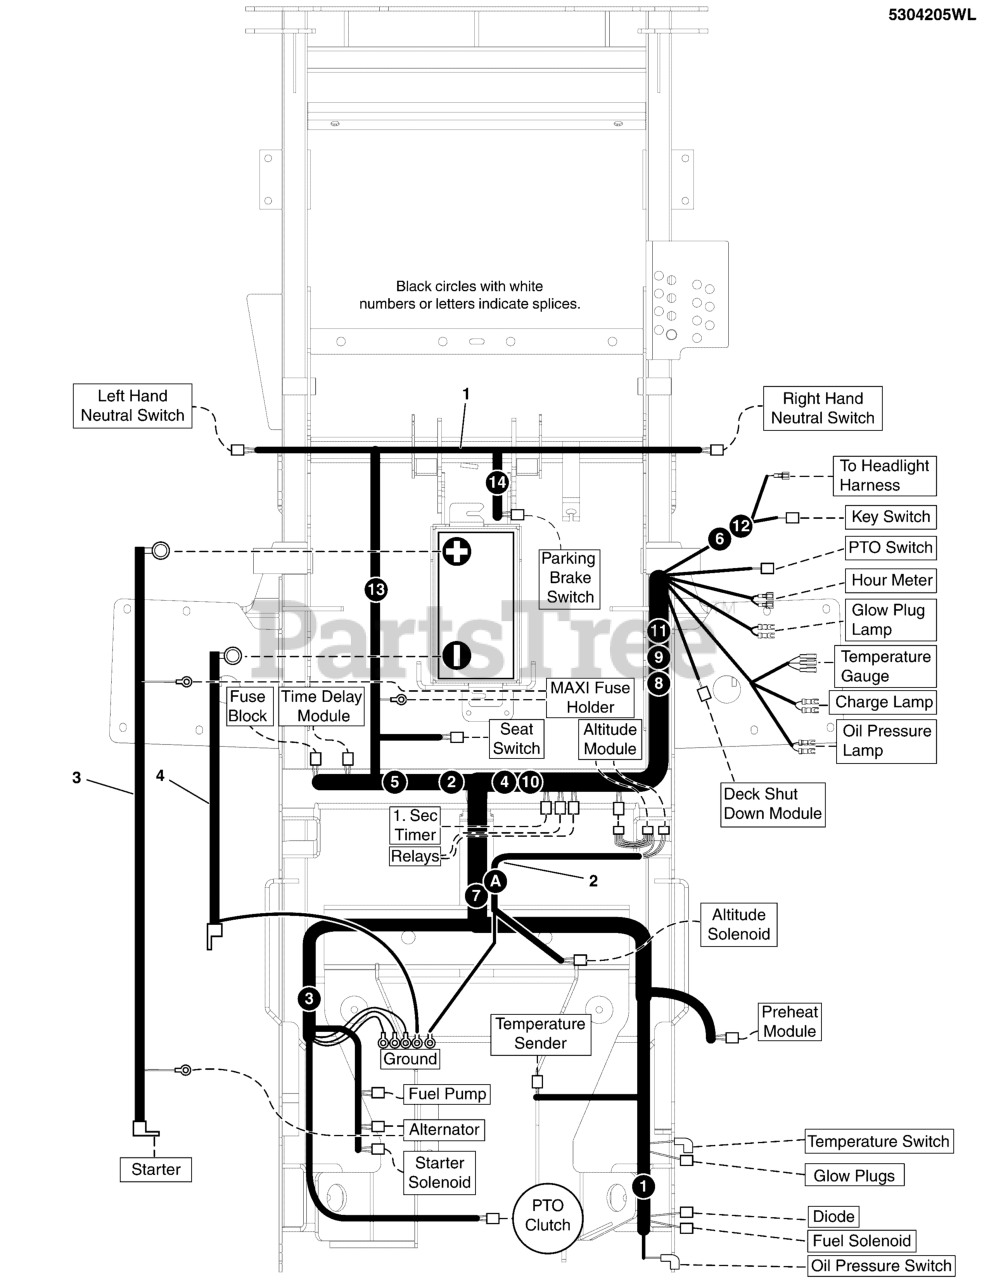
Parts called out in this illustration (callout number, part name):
1	WIRE HARNESS, MAIN, IS2600
2	WIRE HARNESS, ALTITUDE/SOLENOID, IS2600
3	ASSEMBLY, POS BATTERY CABLE, IS2600
4	BATTERY CABLE, NEG
